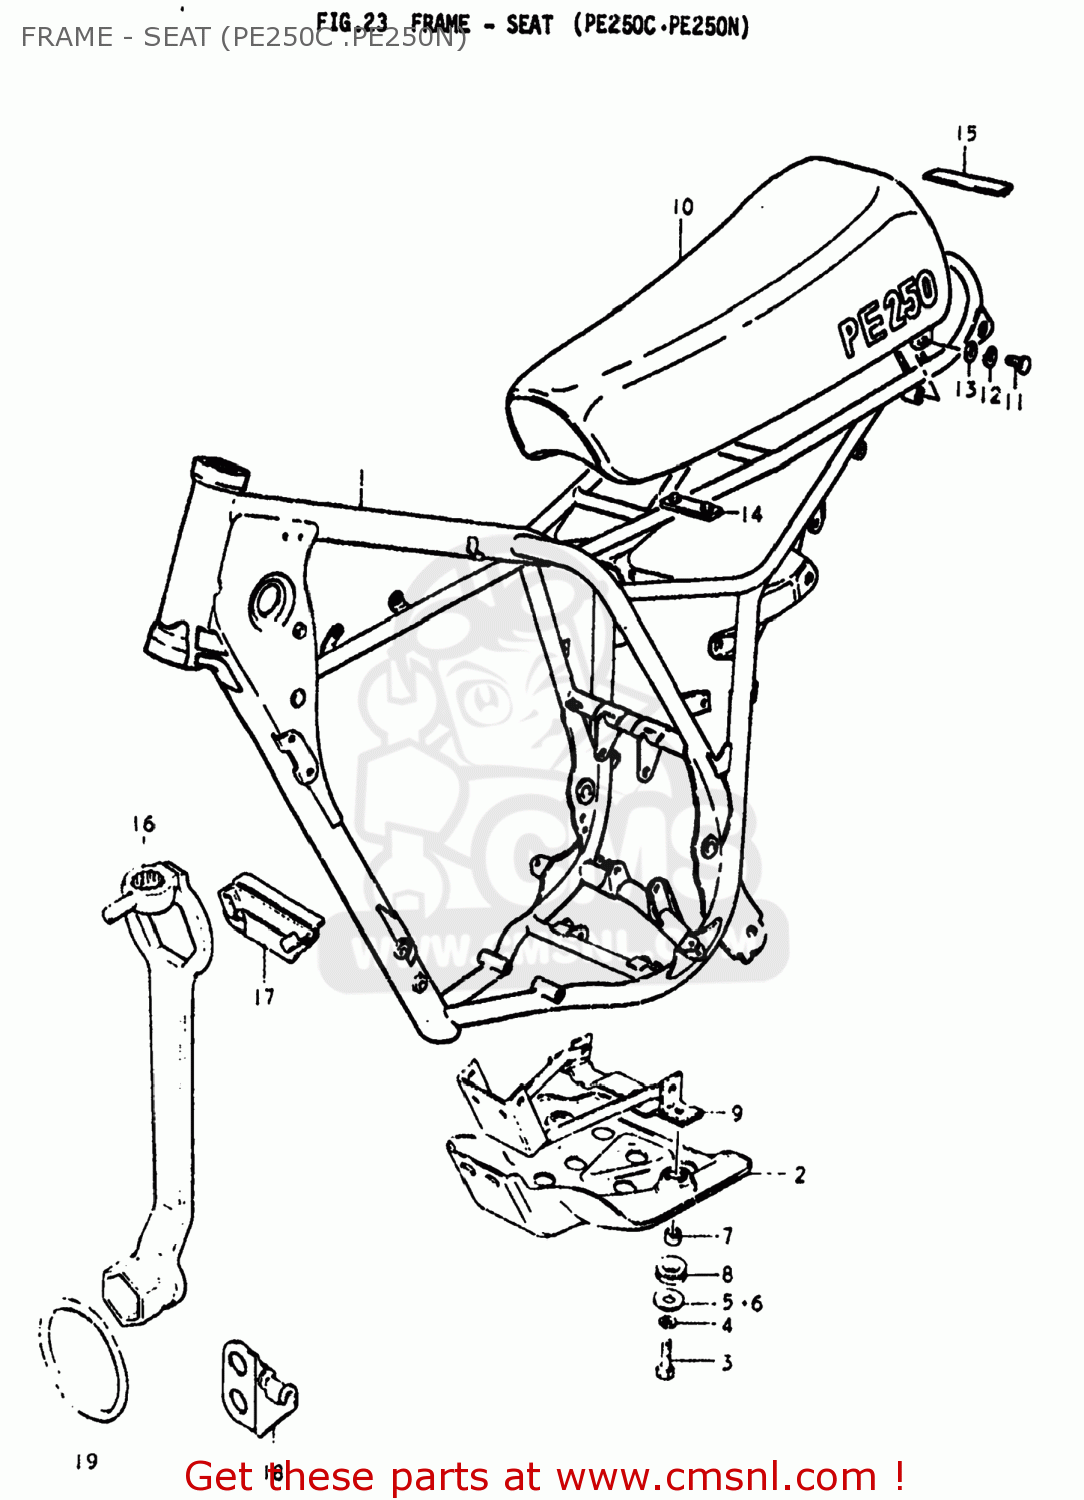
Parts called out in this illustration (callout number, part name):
1	FRAME
2	GROMMET
3	BOLT
4	LOCK WASHER
5	WASHER(8.5X26X1.2)
6	WASHER
7	SPACER (8.8X12X7)
8	CUSHION
9	BRACKET,ENGINE PROTECT
10	SEAT ASSEMBLY
12	BOLT
13	WASHER
14	CUSHION
15	CUSHION,FRAME
16	SPARK PLUG/REAR
17	BRACKET,TOOL FITTING,UPPER
18	BRACKET,TOOL FITTING,LOWER
19	O RING,RR BRAKE CABLE
